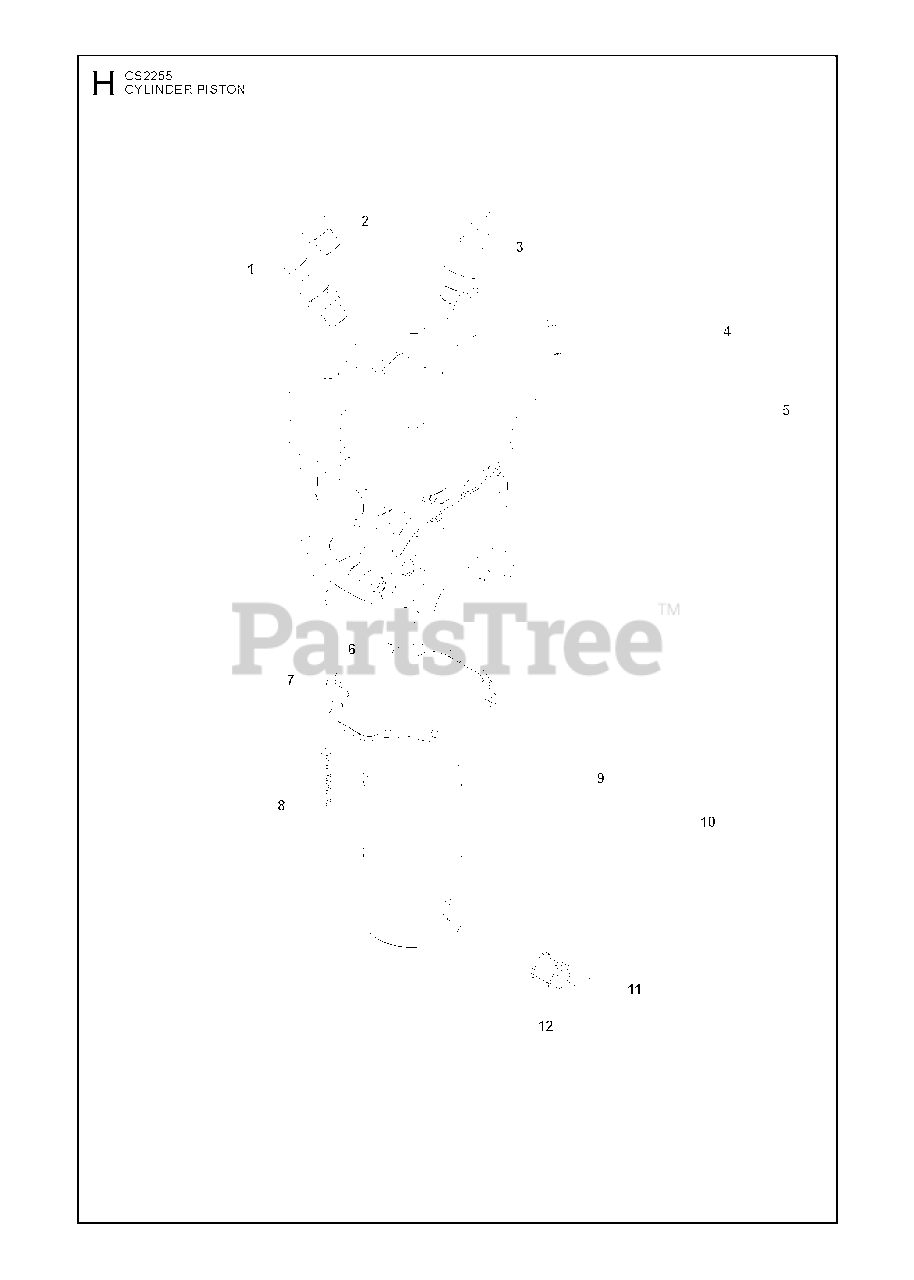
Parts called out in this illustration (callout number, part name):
2	CYLINDER PLUG
3	SPARK PLUG RCJ7Y
4	NIPPLE
9	PISTON RING
10	PISTON CPL.
12	SUPPORT BUSHING
